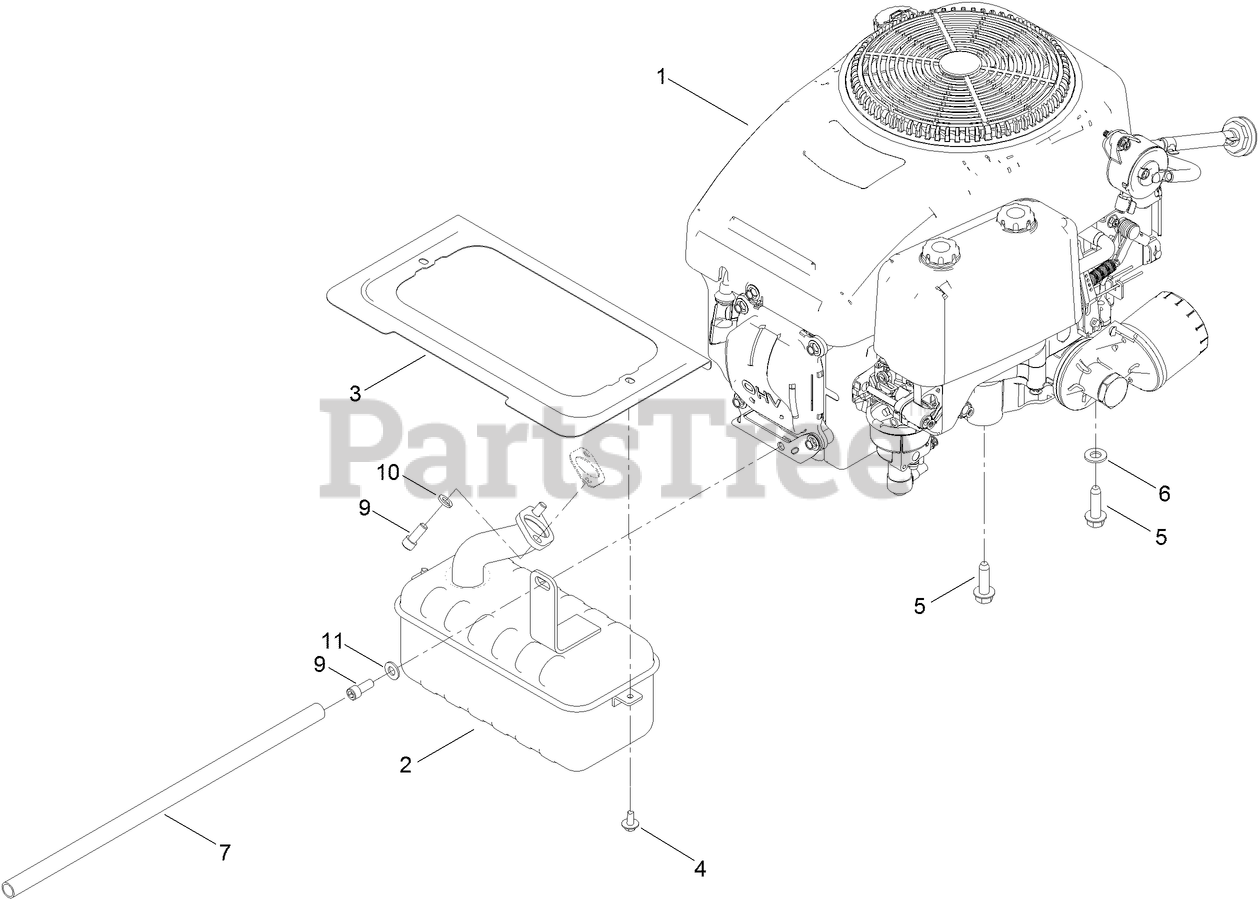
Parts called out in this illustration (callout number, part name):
2	MUFFLER
3	SHIELD-HEAT
4	SCREW-HHFTF
5	SCREW-THD
6	WASHER-FLAT
7	TUBE-DRAIN, OIL
9	SCREW-HSH
10	WASHER-LOCK
11	WASHER-PLAIN
